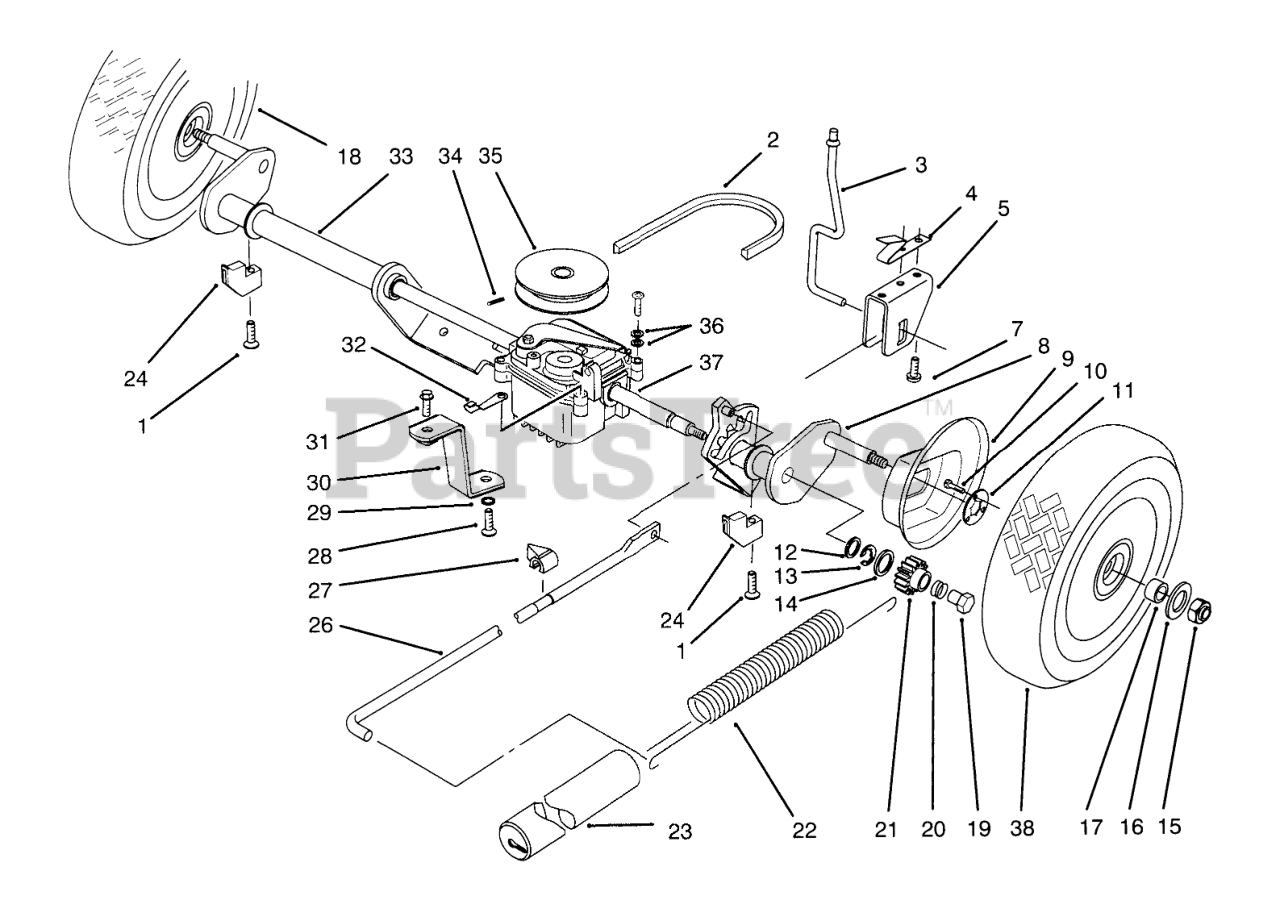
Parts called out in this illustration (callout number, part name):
1	SCREW-RETAINER
2	BELT - V
3	Rod-Trigger
4	SPRING-RETURN, TRIGGER
5	SADDLE-HEIGHT OF CUT
7	SCREW-RH
8	AXLE - REAR
9	COVER-WHEEL
10	SCREW - WHEEL GEAR
11	GEAR-WHEEL
12	WASHER-COVER
13	WASHER-AXLE
14	WASHER-GEAR
15	NUT-HH
16	WASHER-WHEEL
17	BUSHING
18	WHEEL-REAR
19	Bushing-Left
20	Spring-L.H.
22	SPRING-COUNTERBALANCE
23	COVER-SPRING
24	RETAINER - AXLE
26	ROD-LINK
27	INDICATOR-HEIGHT OF CUT
28	SCREW-BRACKET
29	WASHER - BRACKET
30	BRACKET - GEARBOX
31	SCREW - BRACKET
32	HOLDER - CABLE
33	AXLE - REAR
34	PIN - ROLL
35	PULLEY - GEARBOX
36	WASHER
37	ASSEMBLY - GEAR CASE
38	WHEEL-SMART, REAR
